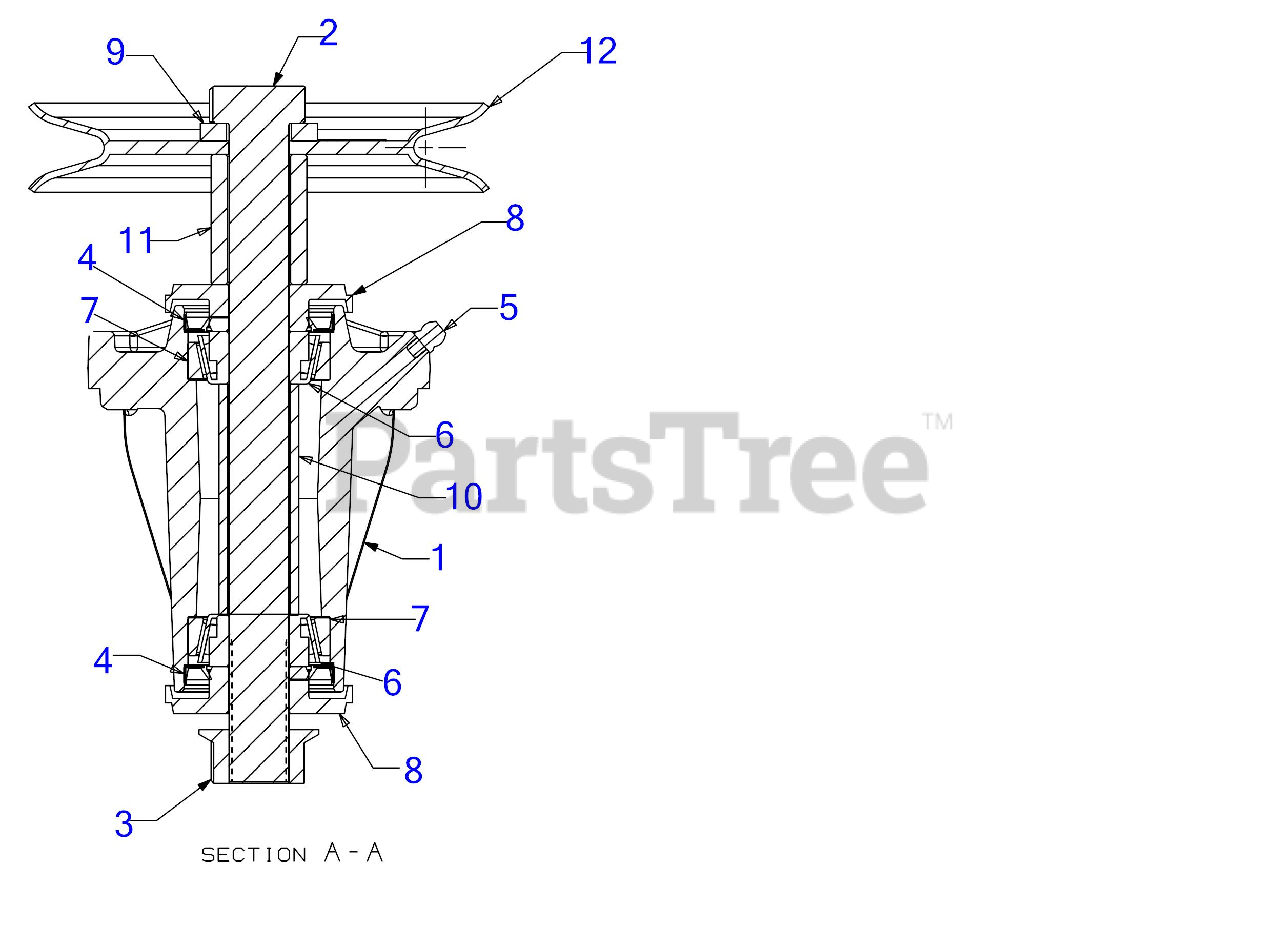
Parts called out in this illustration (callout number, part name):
1	HOUSING
2	SCREW 3/4-16 x 8.25 GR5
3	HEX FLANGE NUT 3/4
4	SINGLE LIP SEAL
5	GREASE FITTING
6	BEARING CONE
7	BEARING CUP
8	DECK SPINDLE SPACER
9	SPACER .812 ID x .218 LG
12	V-PULLEY 5.768 DIA
